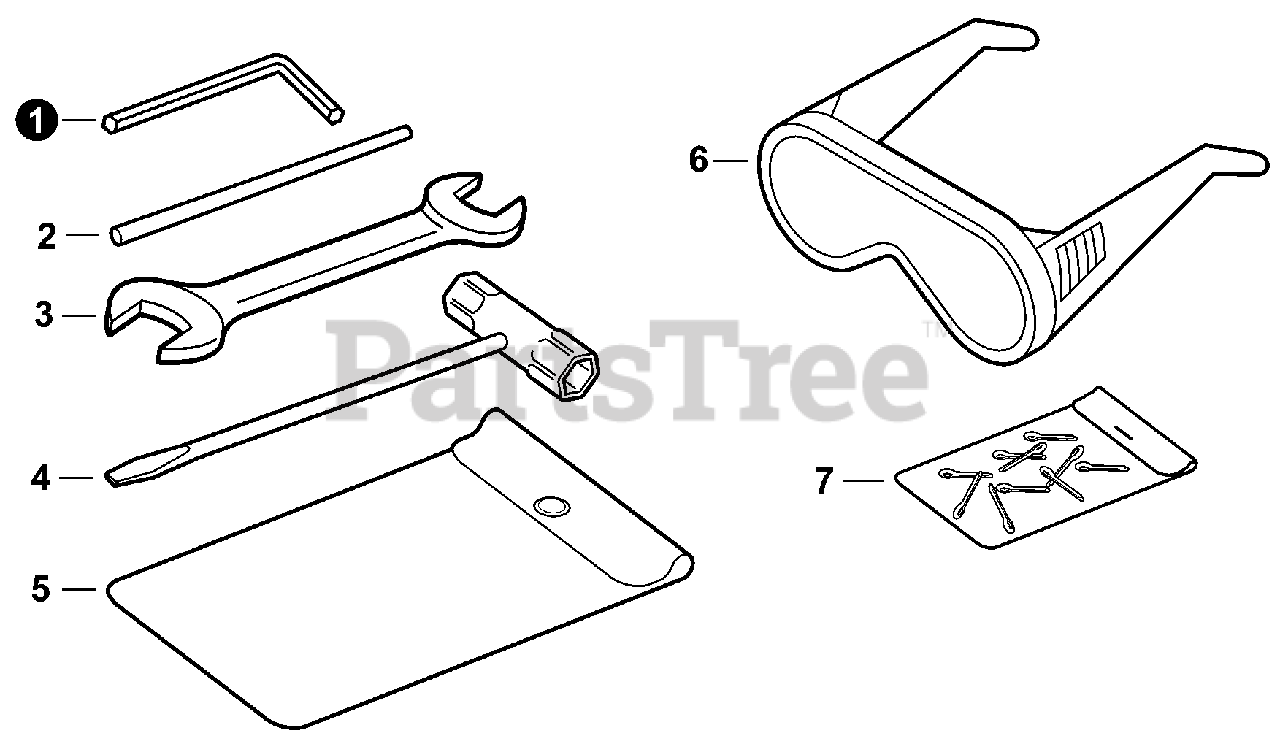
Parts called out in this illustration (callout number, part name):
1	WRENCH, ALLEN 4 MM
2	TOOL, LOCKING 5×120 MM
3	SPANNER 8×10
4	T-WRENCH 17x-19 L200
5	BAG, TOOL
6	GLASSES, SAFETY
7	PIN, COTTER 2×22 (PKG. OF 10)
